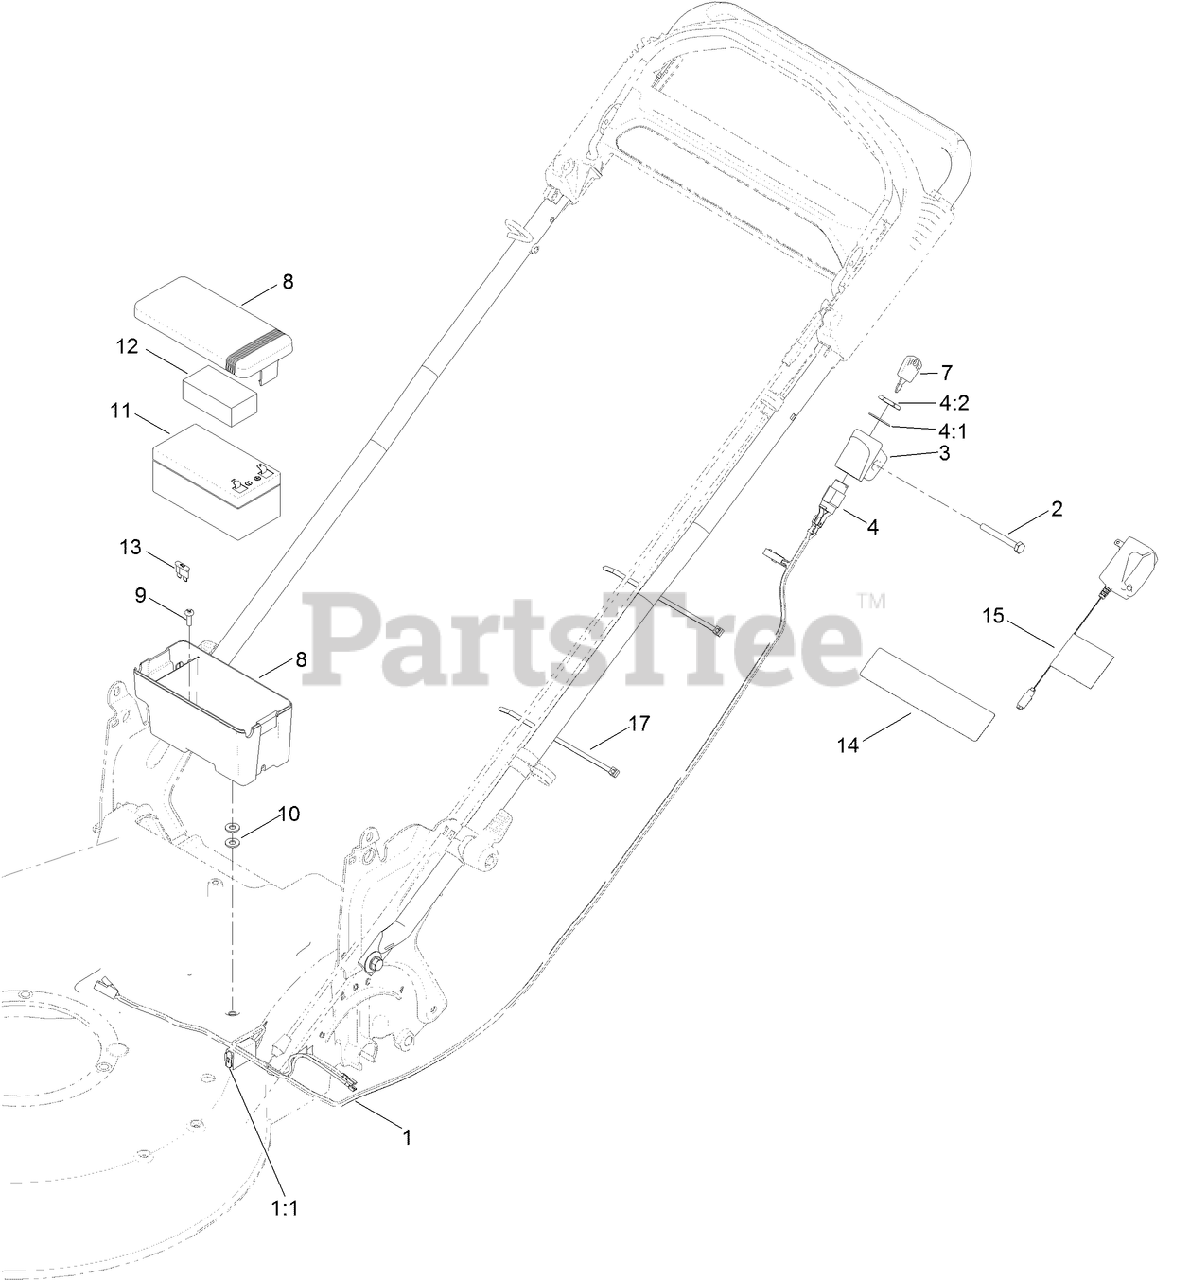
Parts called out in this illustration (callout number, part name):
1	HARNESS-WIRE
1:1	FUSE-40 AMP
2	SCREW-HH
3	MOUNT-SWITCH
4	STARTER SWITCH ASM
4:1	WASHER-LOCK
4:2	NUT-HH
8	BATTERY BOX ASM
10	WASHER-FLAT
11	BATTERY-WET
12	FOAM-BATTERY, TOP
13	FUSE-40 AMP
14	DECAL-WARNING
17	TIE-CABLE
